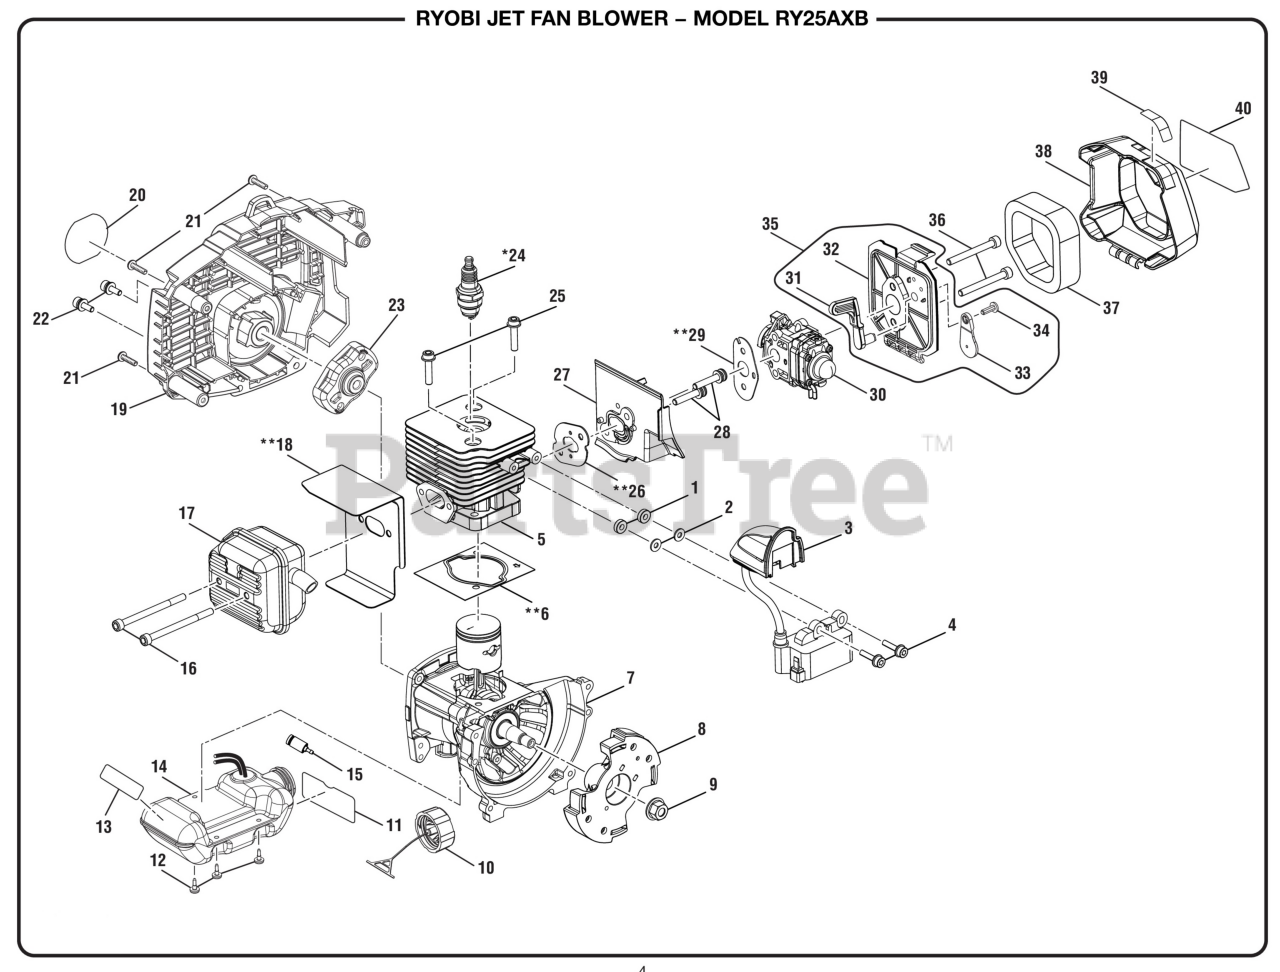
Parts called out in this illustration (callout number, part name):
1	Phenolic Spacer (Ignition Module)
2	Flat Washer (OD10 x ID42 x 1t)
3	Ignition Module
4	Screw (M4 x 22 mm, T20 Torx Slotted Recessed Pan Hd.)
6	Gasket
7	Crankcase Assembly
9	Flange Nut (M8, Flywheel)
10	Fuel Cap Assembly (Inc. Tether)
11	Fuel Mixture Label
12	Shoulder Screw w/Washer (M4 x 14 mm, T25 Torx Truss Hd.)
13	Warning Label (Combustion)
14	Fuel Tank w/Cap Assembly
15	Fuel Filter
16	Cap Screw (M5 x 65 mm, T25 Torx Soc. Hd.)
17	Muffler Assembly
18	Muffler Gasket
19	Rear Housing and Starter Assembly
20	Shoulder Screw (M4 x 14 mm, T25 Torx Truss Hd.
21	Screw (M4 x 1.41 mm x 18 mm, T20 Torx Pan Hd. T.F)
22	Cap Screw w/Washers (M5 x 16 mm, T25 Torx Soc. Hd.)
23	Starter Cup
24	Spark Plug (Champion RCJ6Y)
25	Screw (M5 x 22 mm, T25 Torx Soc. Hd.)
26	Heat Dam Insulator
28	Screw w/Washers (M5 x 30 mm, T25 Torx Pan Hd.)
29	Gasket Carb-Heat Dam
30	Carburetor Assembly
31	Choke Lever
32	Air Box Base
33	Screw (M4 x 12 mm, T20 Torx Pan Hd. S.T.)
34	Screw (M4 x 12 mm, Slotted Recessed Pan Hd.)
35	Airbox Assembly
36	Cap Screw (M5 x 45 mm, T25 Torx Soc. Hd.)
37	Air Filter (Element)
38	Air Box Cover
39	Choke Position Label
40	Starting Instructions Label
